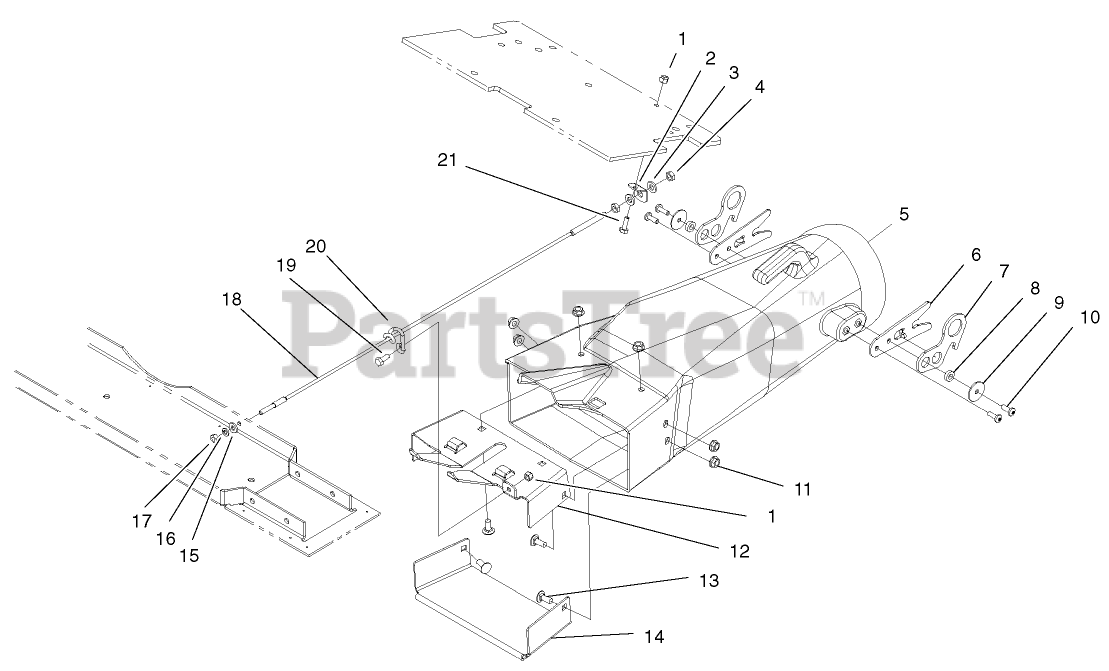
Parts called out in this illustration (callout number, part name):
1	NUT-LOCK, NI
2	BRACKET-SPRING
3	WASHER-PLAIN
4	NUT-JAM
5	PLENUM
6	PLATE-GUIDE
7	PLATE-LATCH
8	SPACER
9	WASHER-FLAT
10	SCREW-TORX
11	NUT-HF
12	PLATE-PLENUM, TOP
13	SCREW-CARR
14	PLATE-PLENUM, BOTTOM
15	WASHER-FLAT
16	WASHER-LOCK
17	NUT-HEX
18	CABLE-TENSION
19	SCREW-HH
20	GUIDE-CABLE
21	SCREW-HH
